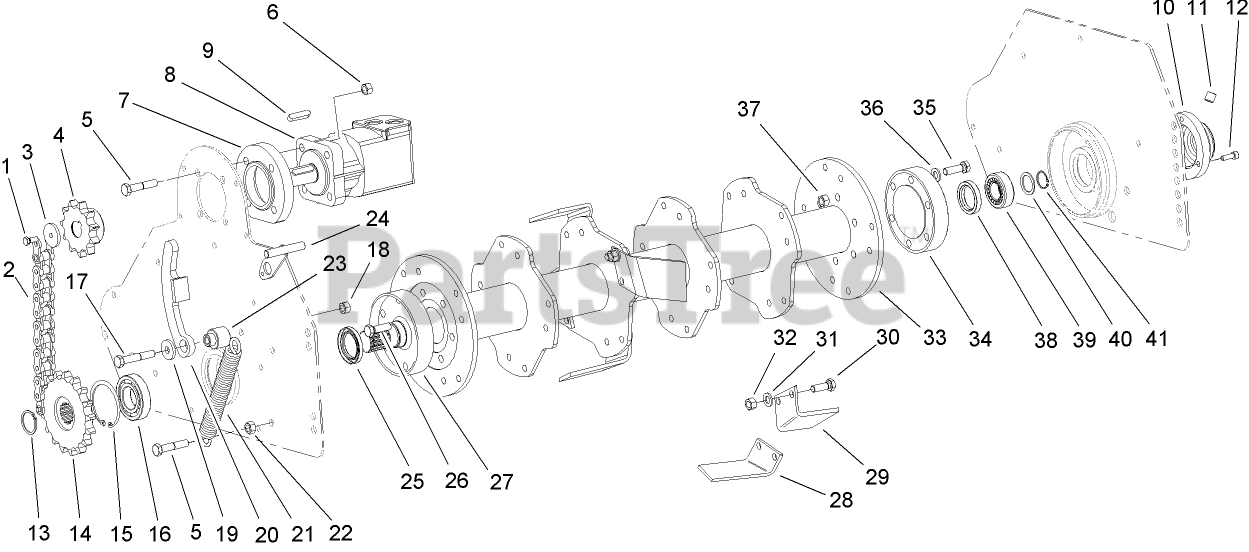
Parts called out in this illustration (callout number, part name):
1	SCREW-HH
2	CHAIN-ROLLER
3	WASHER
4	GEAR-11 TOOTH
5	SCREW-HH
6	NUT-LOCK
7	WASHER-FIXING, MOTOR
8	MOTOR-HYD
9	KEY-MOTOR
10	CAP-END
11	PLUG-BRASS
12	BOLT-HSH
13	CIRCLIP
14	GEAR-17 TOOTH
15	CIRCLIP
16	BEARING ASM
17	SCREW-HH
18	NUT-LOCK
19	WASHER-FLAT
20	TIGHTENER-CHAIN
21	SPRING-EXTENSION
23	BRACING-TUBULAR
24	HANDLE-SPRING
25	RING-PACKING
27	SHAFT-DRIVE
28	BLADE-LEFT
29	BLADE-RIGHT
30	BOLT-HH
31	WASHER-LOCK
32	NUT-HEX
35	SCREW-HH
36	WASHER-LOCK
37	NUT-HEX
38	RING-PACKING
39	BEARING ASM
40	WASHER
41	CIRCLIP
